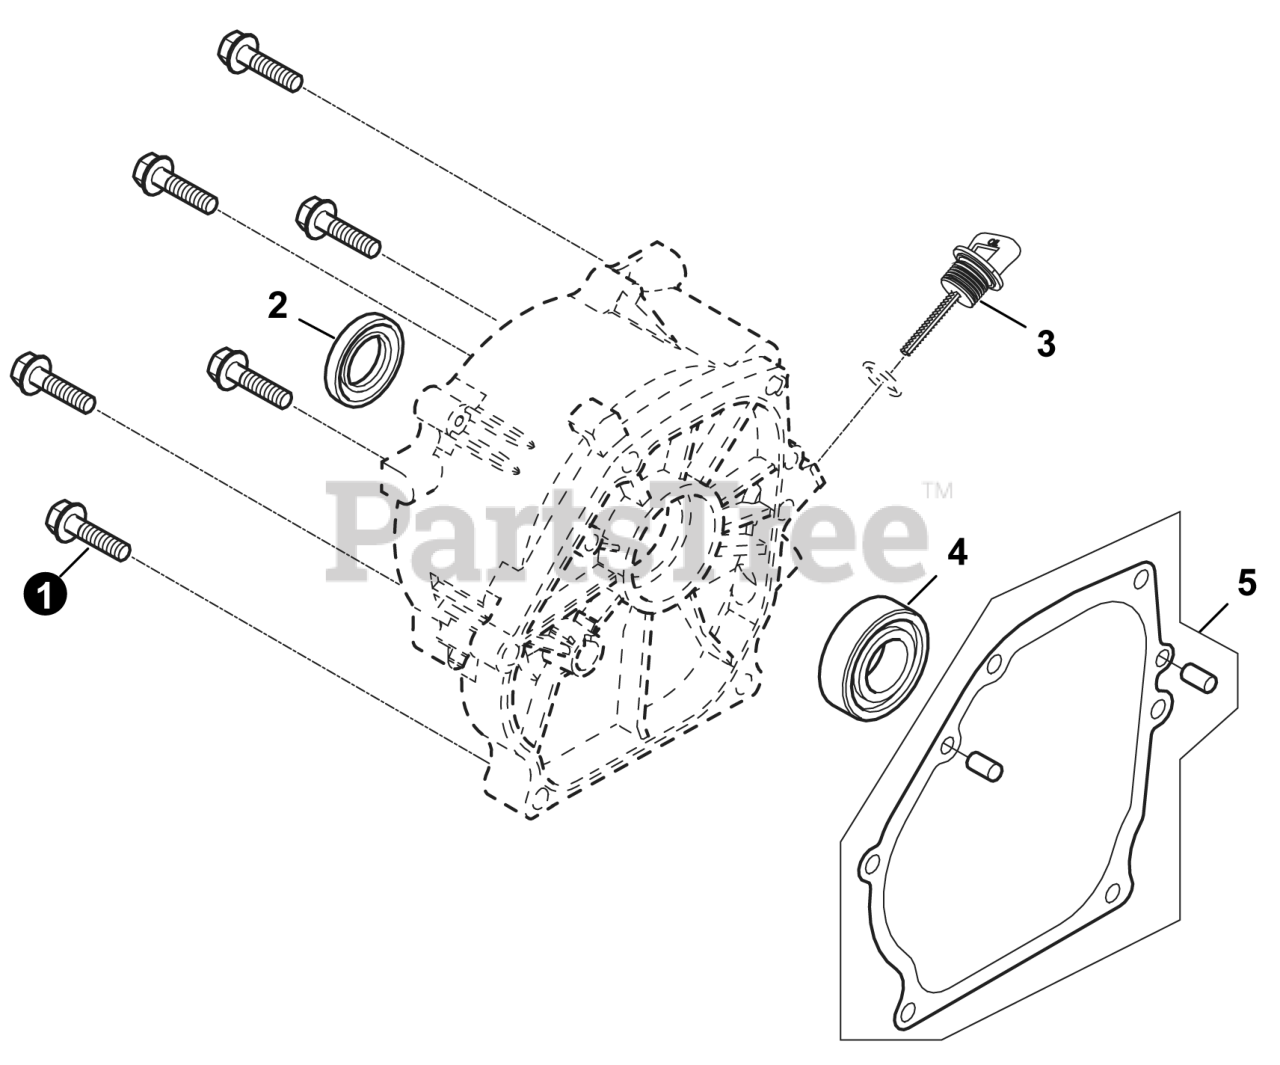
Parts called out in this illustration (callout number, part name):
2	SEAL, OIL
3	DIPSTICK SUBASSEMBLY, OIL
4	BEARING, CRANKSHAFT
5	GASKET, CRANKCASE
